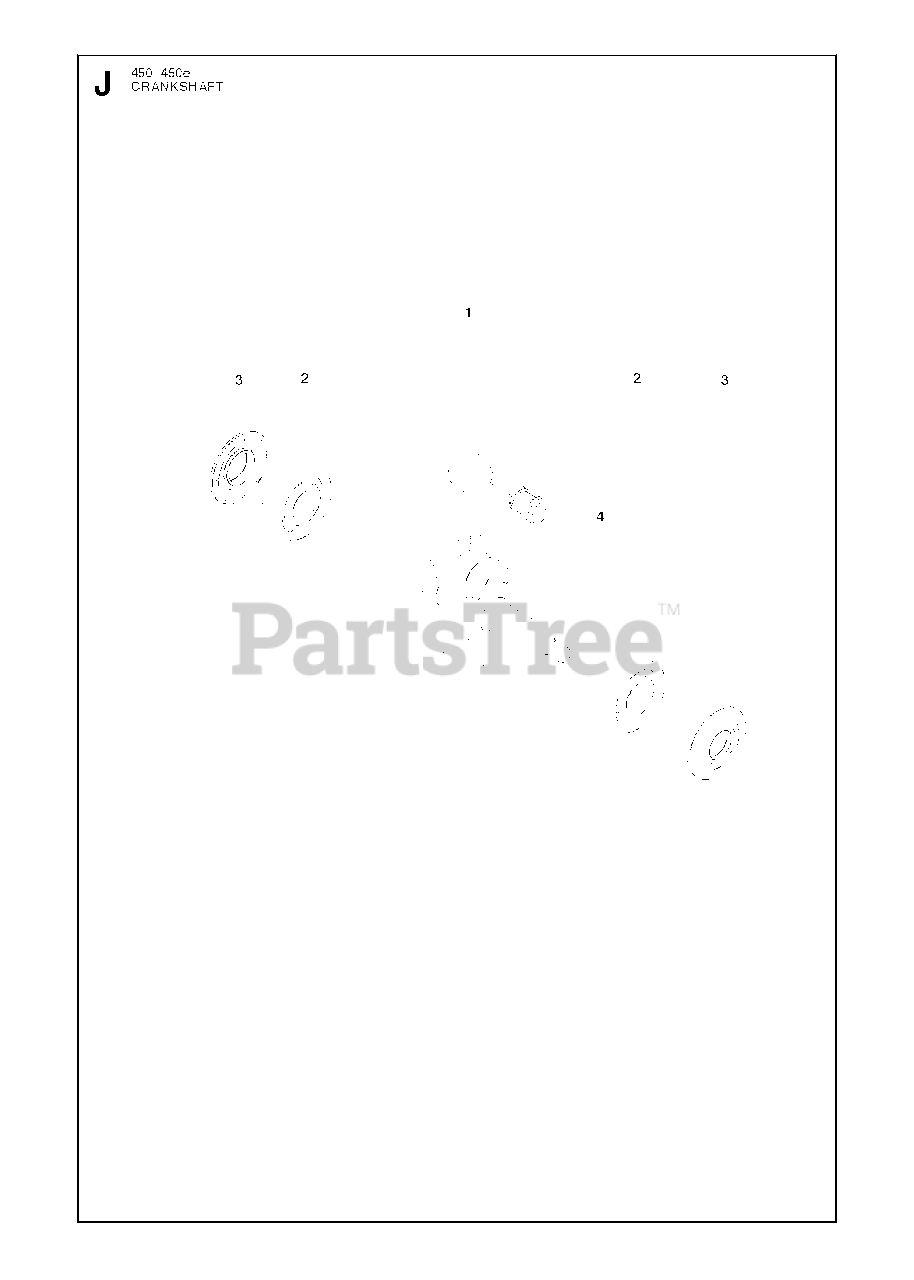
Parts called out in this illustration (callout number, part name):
1	CRANKSHAFT ASSY
2	BEARING
3	SEALING
4	NEEDLE BEARING
